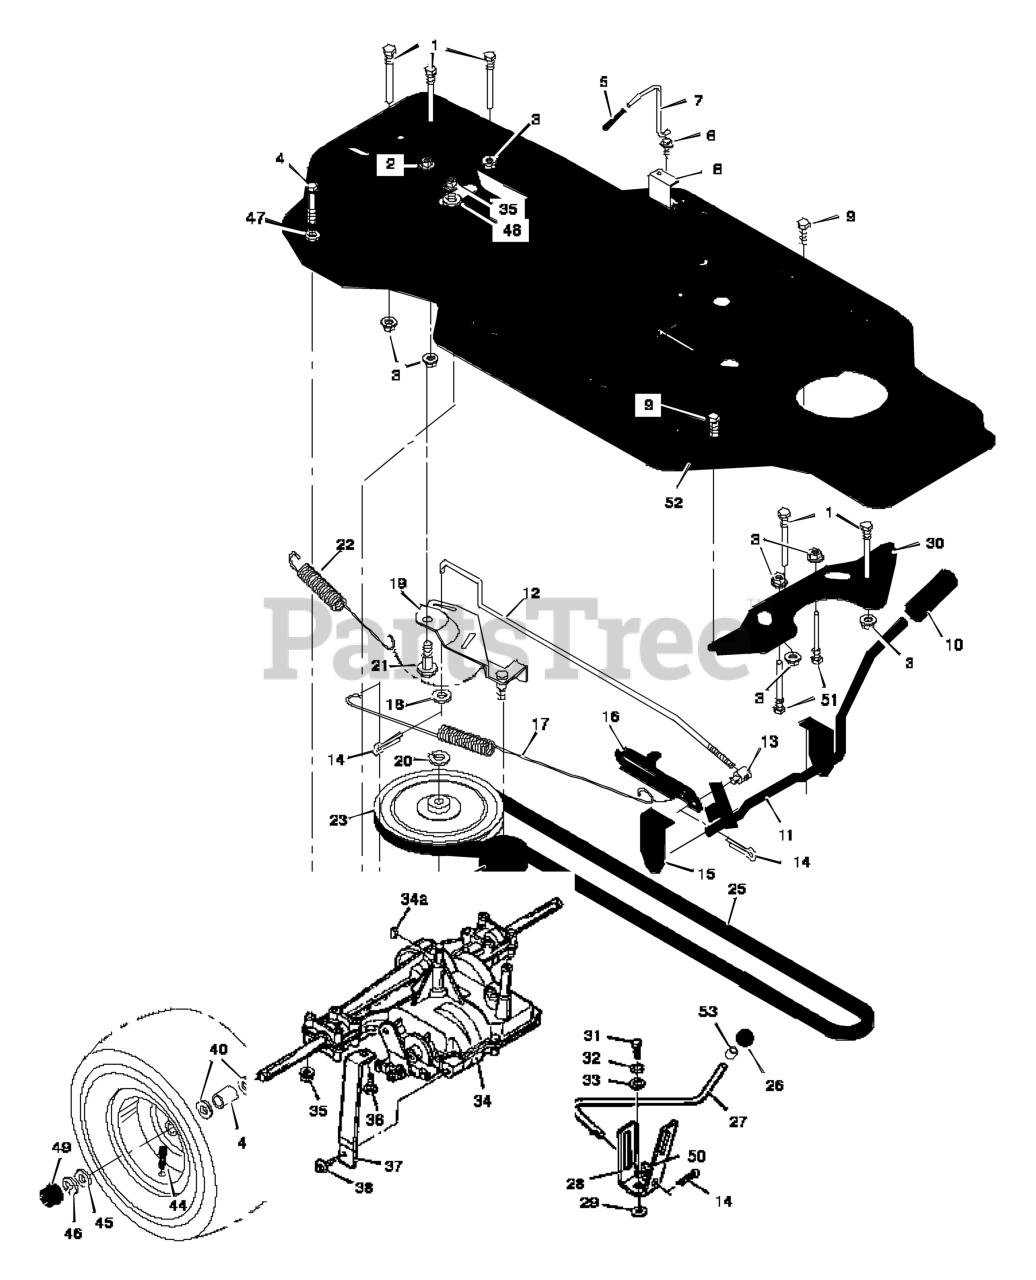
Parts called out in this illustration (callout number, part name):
1	Guide, Belt
2	Locknut, Flange
3	Nut, Flange
4	Bolt, Hex
7	Rod, Control
8	Guide, Bracket
10	Clutch and Brake Pedal
11	Lever Assembly
12	Rod, Clutch
13	Nut, Adjustable
14	Pin, Cotter
15	Bracket, Support
16	Latch, Park Brake
17	Spring, Brake Extension
18	Washer
19	Bracket Assembly, Idler
20	Ring, Retainer
21	Bolt, Shoulder
22	Spring, Drive Extension
23	Pulley, Motion Drive
24	Pulley, Backside Idler
25	Belt, Motion Drive
26	Knob, Shift Lever
27	Lever, Shift
28	Yoke, Shift
30	Plate, Belt Guide
31	Bolt, Hex
32	Lockwasher
34	Transaxle, Peerless **
34A	Woodruff Key No. 9
35	Nut, Flange
36	Bolt, Carriage
37	Support, Transaxle
39	Key, Square
41	Spacer, Transaxle
43	Wheel & Tire Assembly
44	Stem, Valve
47	Washer
49	Hub Cap
50	Washer
51	Guide, Belt
52	Frame Assembly
53	Ring, Tolerance
